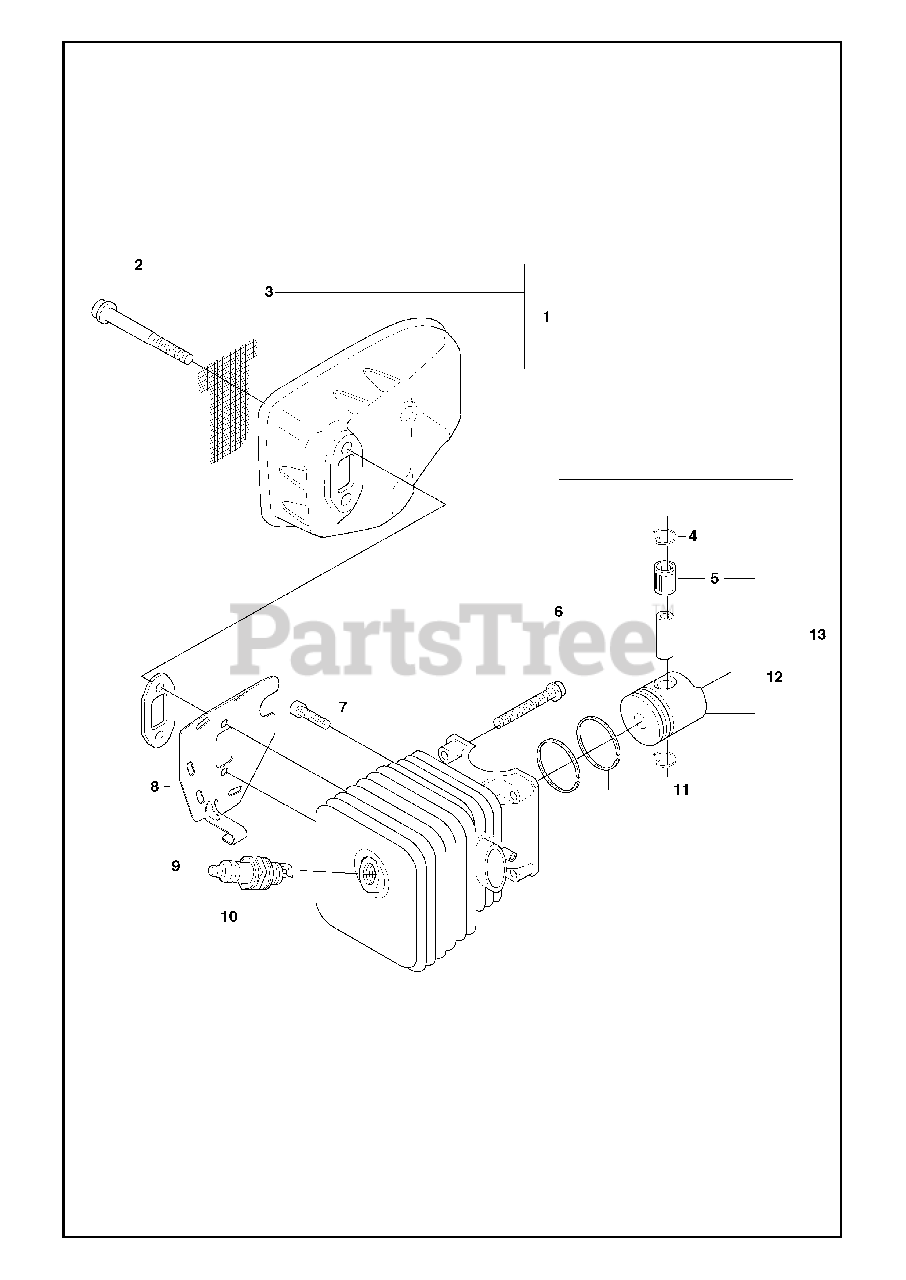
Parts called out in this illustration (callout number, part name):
6	SCREW MC6S 5X35
7	SCREW
9	AIR CONDUCTOR
10	SPARK PLUG RCJ7Y
